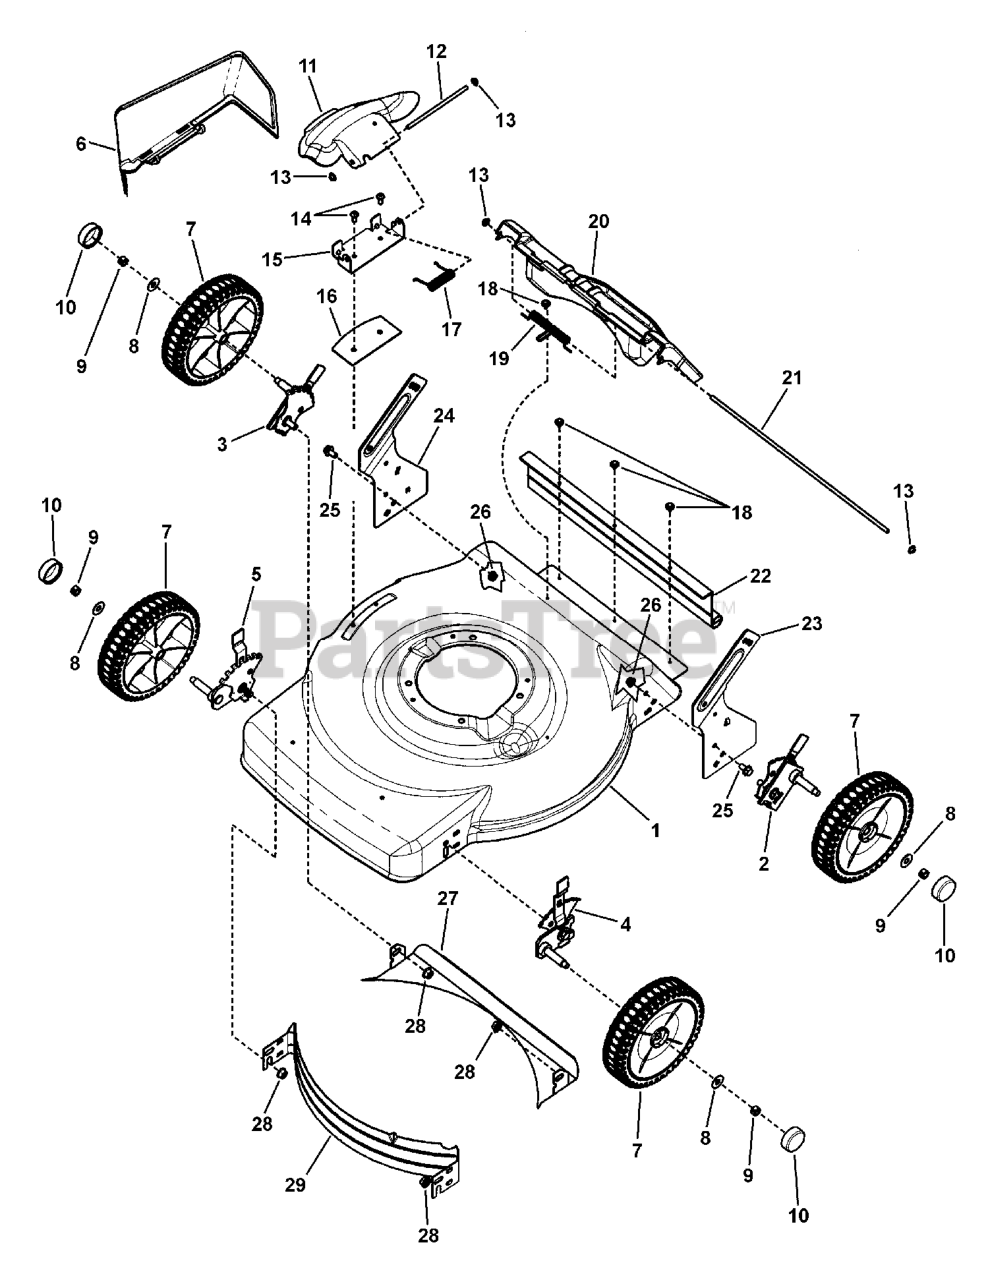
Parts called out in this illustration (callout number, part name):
1	DECK, 22" Walk, Push 3-N-1
2	ASSY, Height-of-Cut, Left Rear, Murray 7 Position
3	ASSY, Height-of-Cut, Right Rear, Murray 7 Position
4	ASSY, Height-of-Cut, Left Front, Murray 7 Position
5	ASSY, Height-of-Cut, Right Front, Murray 7 Position
6	SIDE CHUTE, Plastic, Black
7	ASSY, Wheel, 8"x 2" Idle, NB Murray Tread, Gray
8	WASHER, 1" O.D. x .387 I.D. Flat
9	NUT, 3/8-16 Hex Center Lock, YZ
10	HUBCAP, Round, Black
11	COVER, Mulch, Plastic, Black
12	ROD, Chute Pivot (1/4" Dia. x 5.55")
13	PUSHNUT, 1/4"
14	SCREW, 1/4-20 x .550 Pan Head Self-Tap (Torx)
15	BRACKET, Chute
16	PLATE, Mulch, 22" RB Scott's
17	SPRING, Chute (Torsion)
18	SCREW, #10-24 x 1/2" Hex Washer Self-Tap (Sems)
19	SPRING, Torsion, Rear Door, 22" Walk Mower
20	DOOR, Rear Discharge, 22" Walk Mower
21	ROD, Pivot, Rear Door (1/4" Dia. X 17-1/2")
22	GUARD, Rear
23	BRACKET, Lower Handle, LH
24	BRACKET, Lower Handle, RH
25	BOLT, 5/16-18 x 5/8" Hex Flange Lock, GR 5 YZ
26	NUT, 5/16-18 Flange Lock, YZ
27	BAFFLE, Rear, 22" Deck
28	NUT, 3/8-16 Hex Flange Lock, GR 5
29	BAFFLE, Front, 22" WBM
